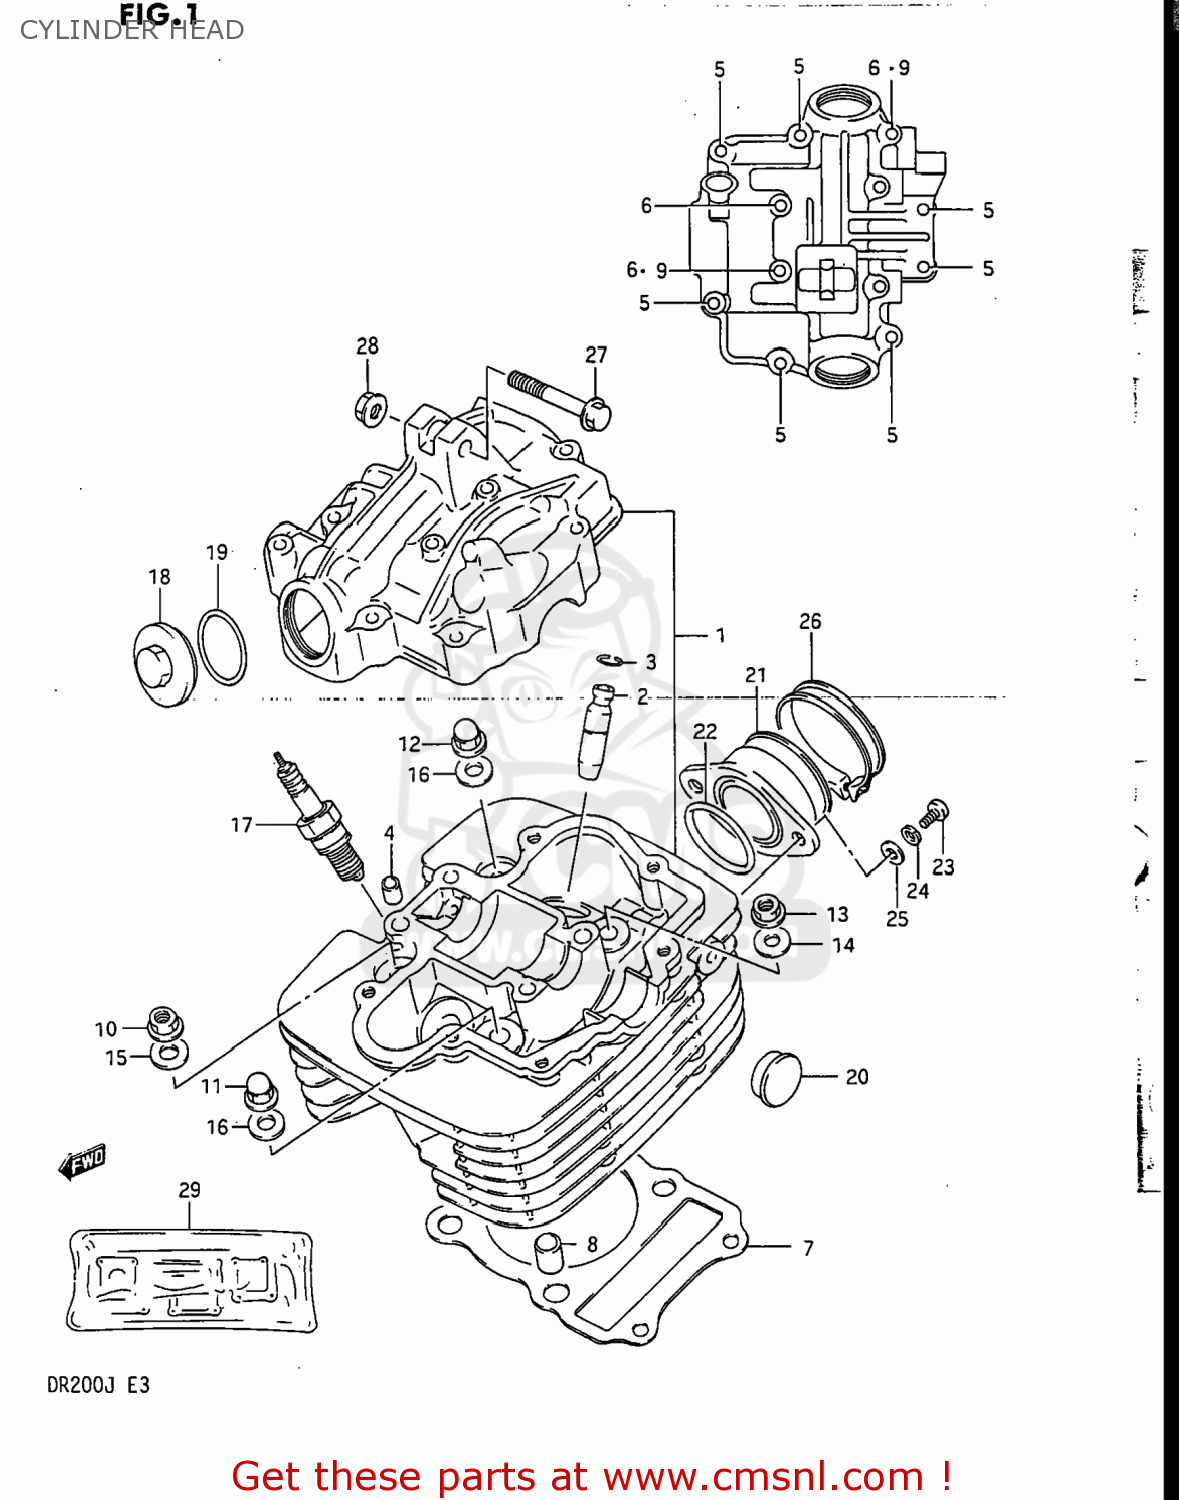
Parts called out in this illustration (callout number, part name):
1	HEAD ASSEMBLY,CYLINDER
2	GUIDE,VALVE
3	RING,SNAP
4	PIN(6.2X8X11)
5	BOLT 6X35
6	BOLT ,6X60
7	GASKET,CYLINDER HEAD (NAS)
8	PIN
9	WASHER
10	NUT 8MM
11	NUT (8MM)
12	NUT
13	NUT
14	WASHER (8.5X19X2.3)
15	WASHER(8.5X19X2.3)
16	GASKET (NAS)
17	SPARK PLUG D8EA
18	CAP,INSPECTION
19	O RING(D:3,ID:29.5)
20	PLUG(OD:22.5)
21	PIPE,INTAKE
22	O-RING,INTAKE PIPE
23	SCREW
24	WASHER,LOCK
25	WASHER
26	CLAMP
27	BOLT 8X50
28	NUT
29	GASKET SET
